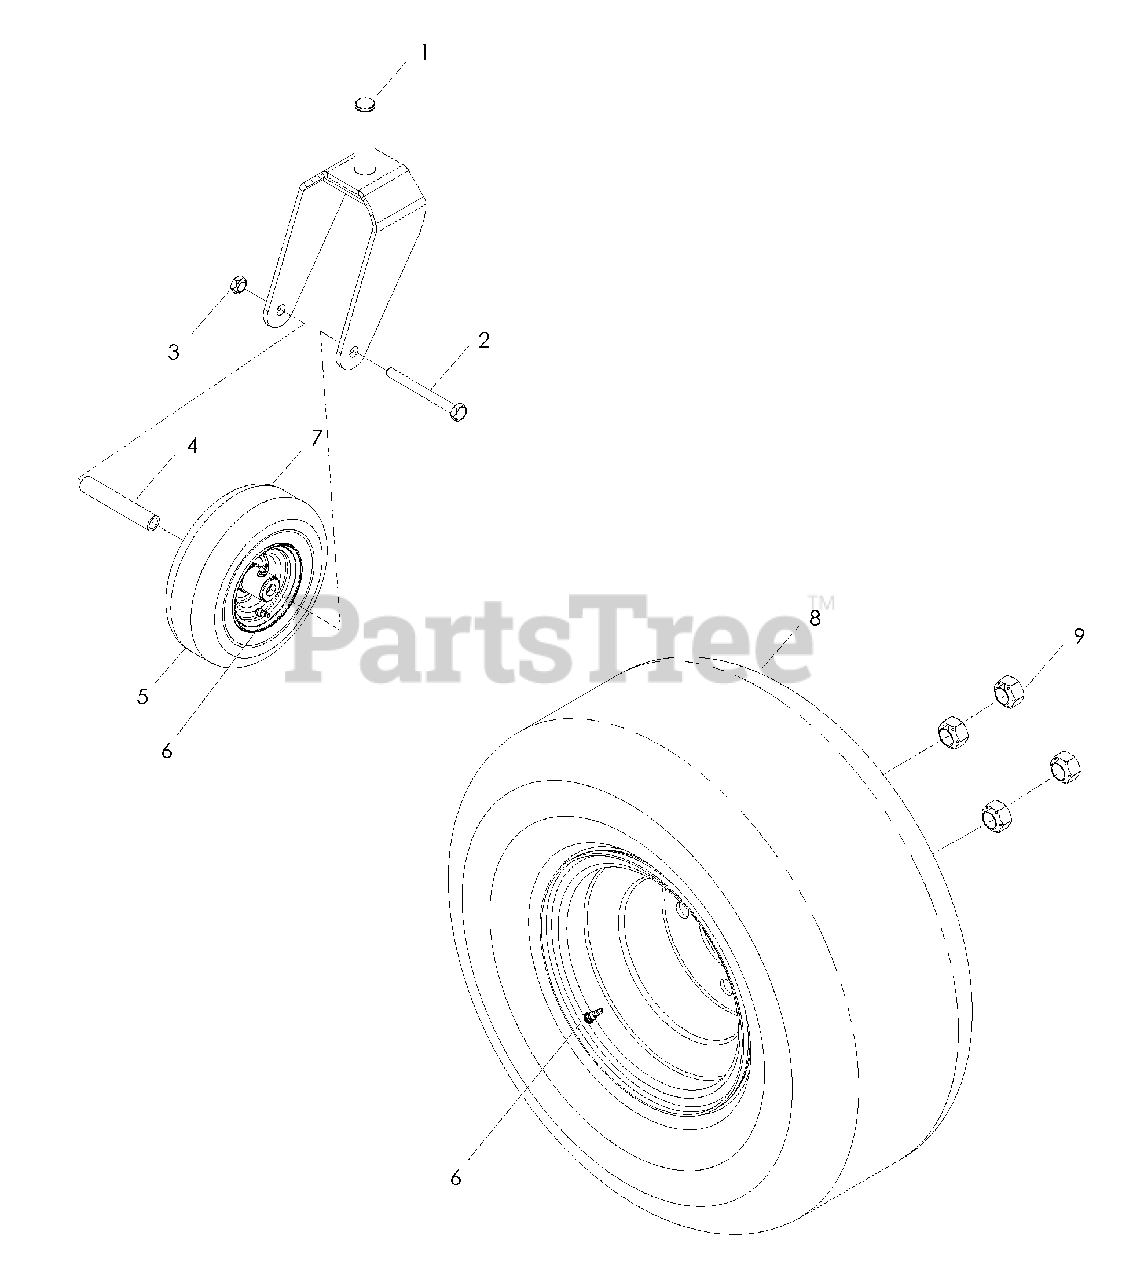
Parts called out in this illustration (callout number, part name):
1	CASTER
2	HCS, 1/2-13 x 5 1/2
3	NUT, 1/2-13, NYLOC
5	CASTER WHEEL ASSM
6	VALVE STEM
7	TIRE 11 x 3.5-5
8	RR WHEEL ASSM 18 x 8.5-8
